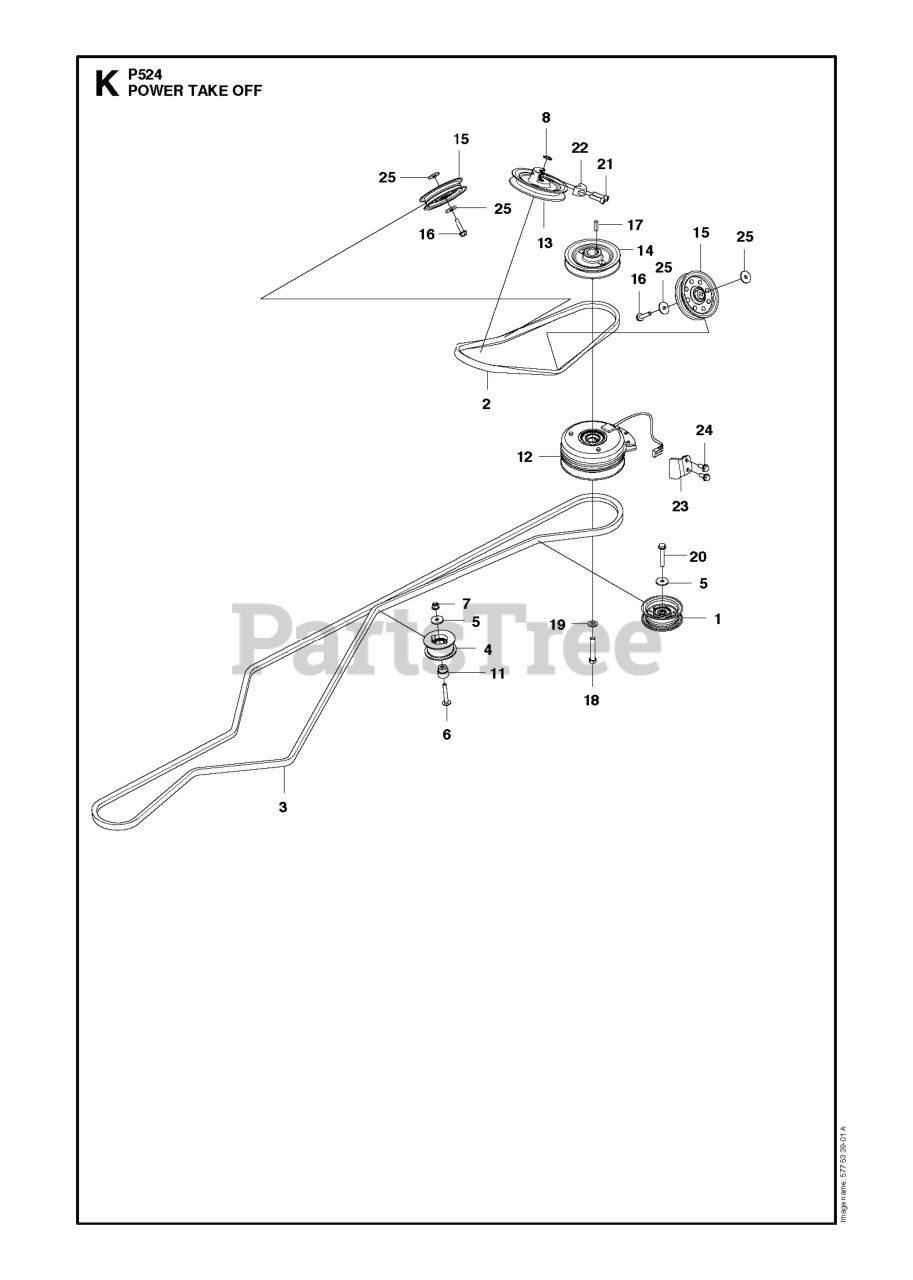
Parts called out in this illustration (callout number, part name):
4	BELT TENSIONER WHEEL ASSY
6	SCREW
7	NUT FLANGE
8	RETAINING RING
16	SCREW EHHFM
20	SCREW EHHFM
